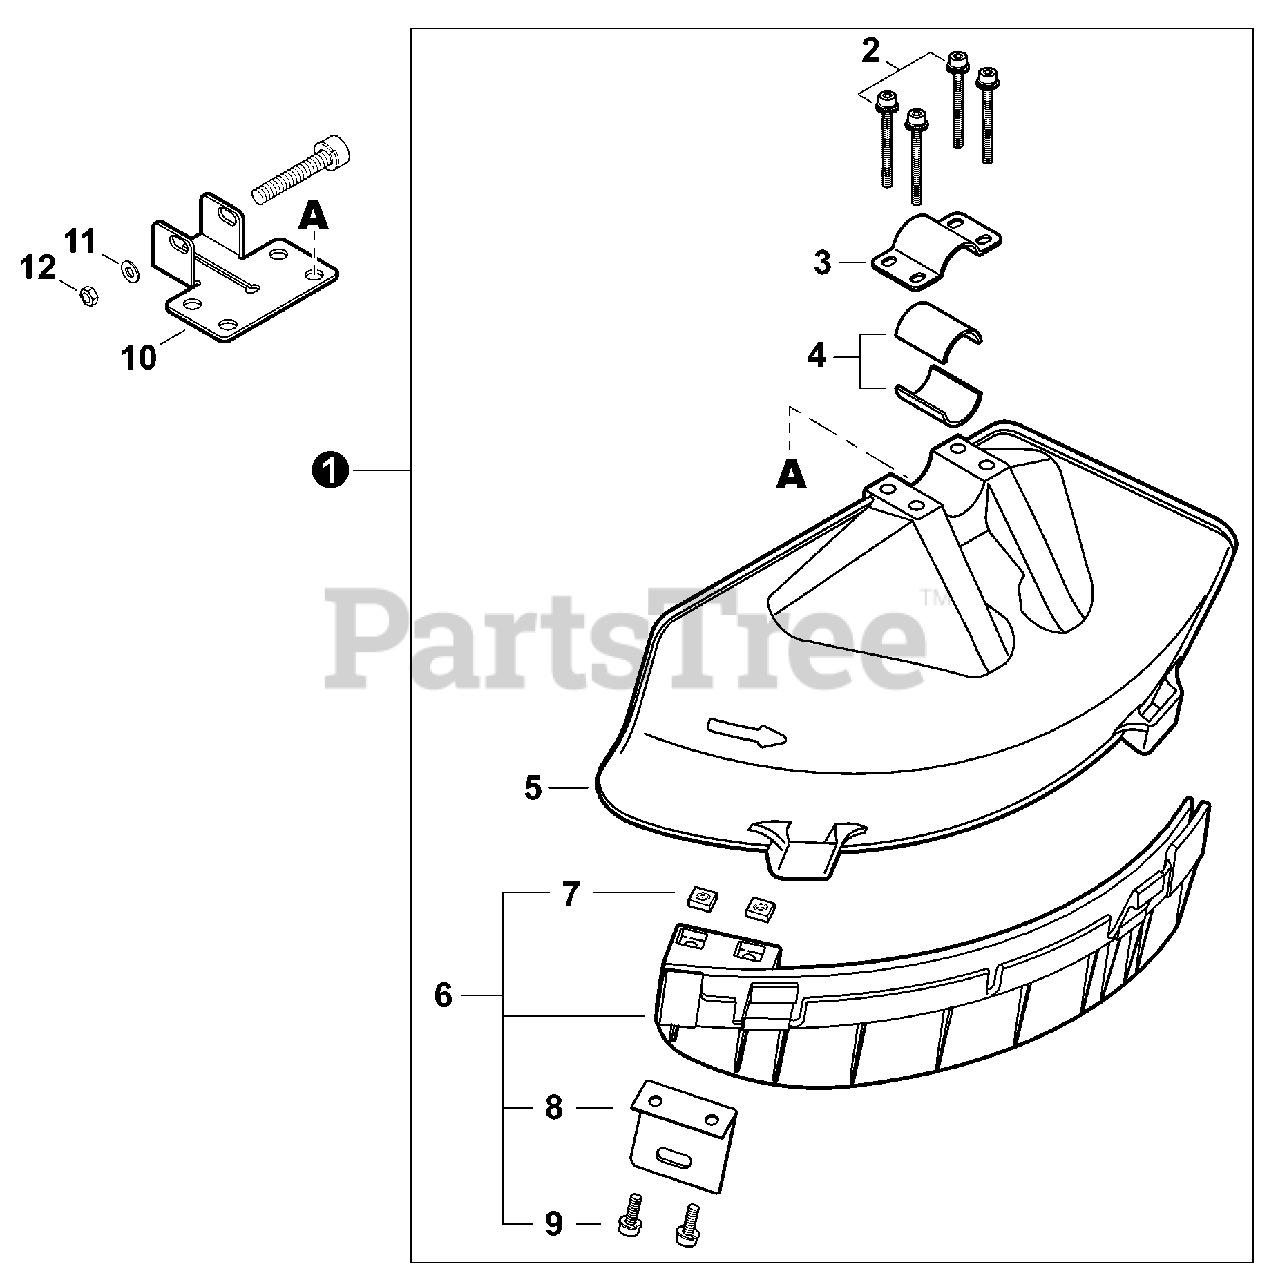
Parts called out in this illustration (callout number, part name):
1	DEBRIS SHIELD KIT
2	BOLT M5×45
3	CLAMP, UPPER
4	SPACER 24
5	SHIELD, DEBRIS PLASTIC
6	DEBRIS SHIELD EXTENSION ASSY
9	BOLT 5×16
10	PLATE, SHIELD MOUNTING
11	WASHER 5.5×12×0.8
12	NUT M5
